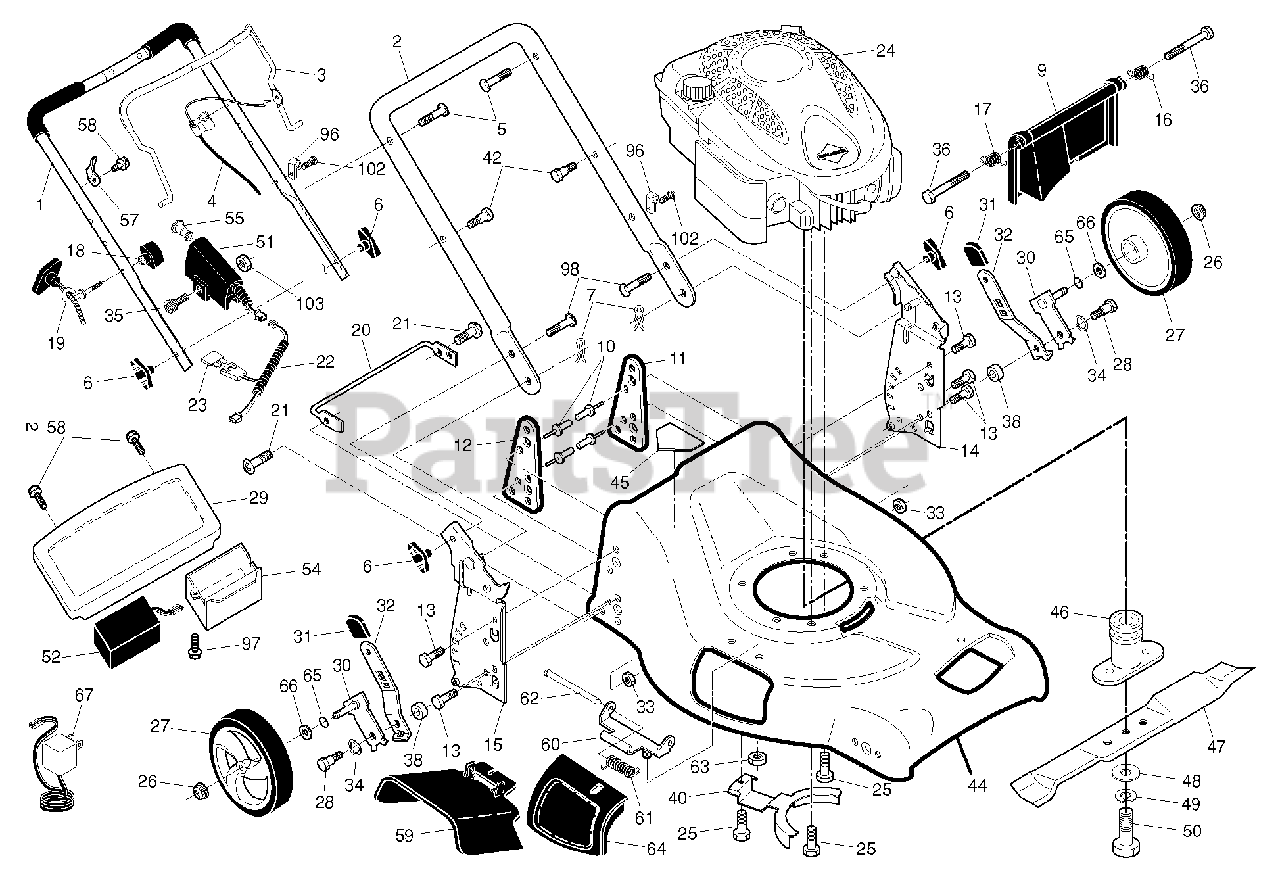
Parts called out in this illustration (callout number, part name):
1	HANDLE.ASM.UP.BS.AW2.GRIP.BLAC
2	HANDLE.LOWER.21FGD.ES.NB.BLACK
4	CABLE.ASM.ZONE.CONTROL
5	BOLT, HANDLE 5/16-18X1.75
6	KNOB, DEFLECTOR
7	HAIRPIN COTTER
9	REAR DOOR ASSEMBLY
10	RIVET BLIND
11	SUPPORT BRACKET LH
12	BRACKET.SUPRT.RH.21.FWGD
13	SCREW 14-20 X 5/8
14	Handle Bracket Assembly, LH 21 Fwgd
15	BRACKET.ASM.HANDLE.RT.21.FWGD
16	SPRING.REAR.DOOR.EZ.21.LT
17	SPRING.REAR.DOOR.EZ.21.RT
18	T-Knob, New Rope Guide
19	Rope Guide, Blk Zinc Chrom
21	SCREW
22	HARNESS,WIRE.ES.21FGD.PUSH BUT
23	FUSE, 40A
25	BOLT 3/8-16X1-1/8
26	NUT.HEX.FLANGE.3/8-16.LOCKNUT
28	SHOULDER BOLT 5/16-18
29	PANEL.TRIM.21.FWGD.ES
31	SELECTOR KNOB
32	SPRING.SELECTOR.21RD.HTTRT.BZP
33	NUT.71038.31-18.HEX.NYLOCK
34	WASHER FLAT
35	BOLT.M6-1X40.T30
38	SPACER.HEIGHT.ADJUSTER
40	BRACKET.ENG/BELTKEEPER
42	SCREW.SHOULDER.HH.10X.281X.6
45	DECAL.INTERNATIONL.CUTFINGER
47	BLADE.21.PUSH
48	WASHER,HARDEN
49	LOCKWASHER
50	SCREW, HEX HD 3/8-24 X 1-3/8
51	HARNESS.ASM.21.FGD.PUSH.BUTTON
52	BATTERY.AMP.CONNECTOR
54	BOX.BATTERY.TRIM
55	BUTTON.PUSHBUTTON.ES
57	BRACKET.UPSTOP.RT
59	DISCHARGE DEFLECTOR
60	HINGE BRACKET ASSEMBLY
61	SPRING.TORSION
62	ROD.HINGE.21
63	LOCKNUT
64	DOOR.MULCH.21.REAR
65	O-RING..070X.487.NEOPRENE
66	WASHER PM
96	CLIP.CABLE.BLK
98	BOLT
102	FASTENER.PUSH.O.250X0.783
103	NUT.M6-1 NYLOC
